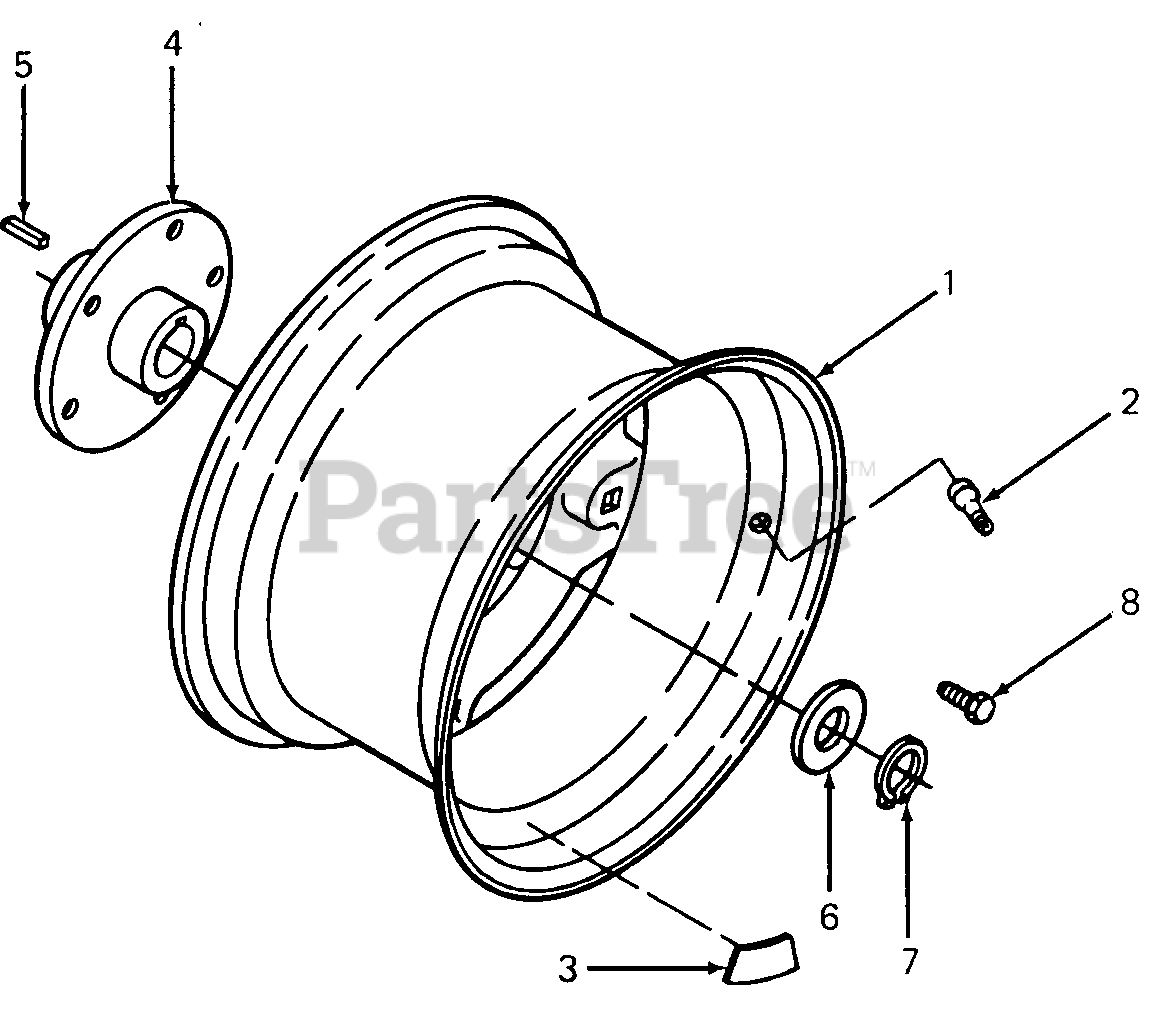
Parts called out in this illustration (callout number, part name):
3	Label, Inflation
6	Washer, Flat, 1.031 X 2.0 X .054 Thk
7	Ring, Retaining, 1.0 Dia
8	Bolt, Wheel
